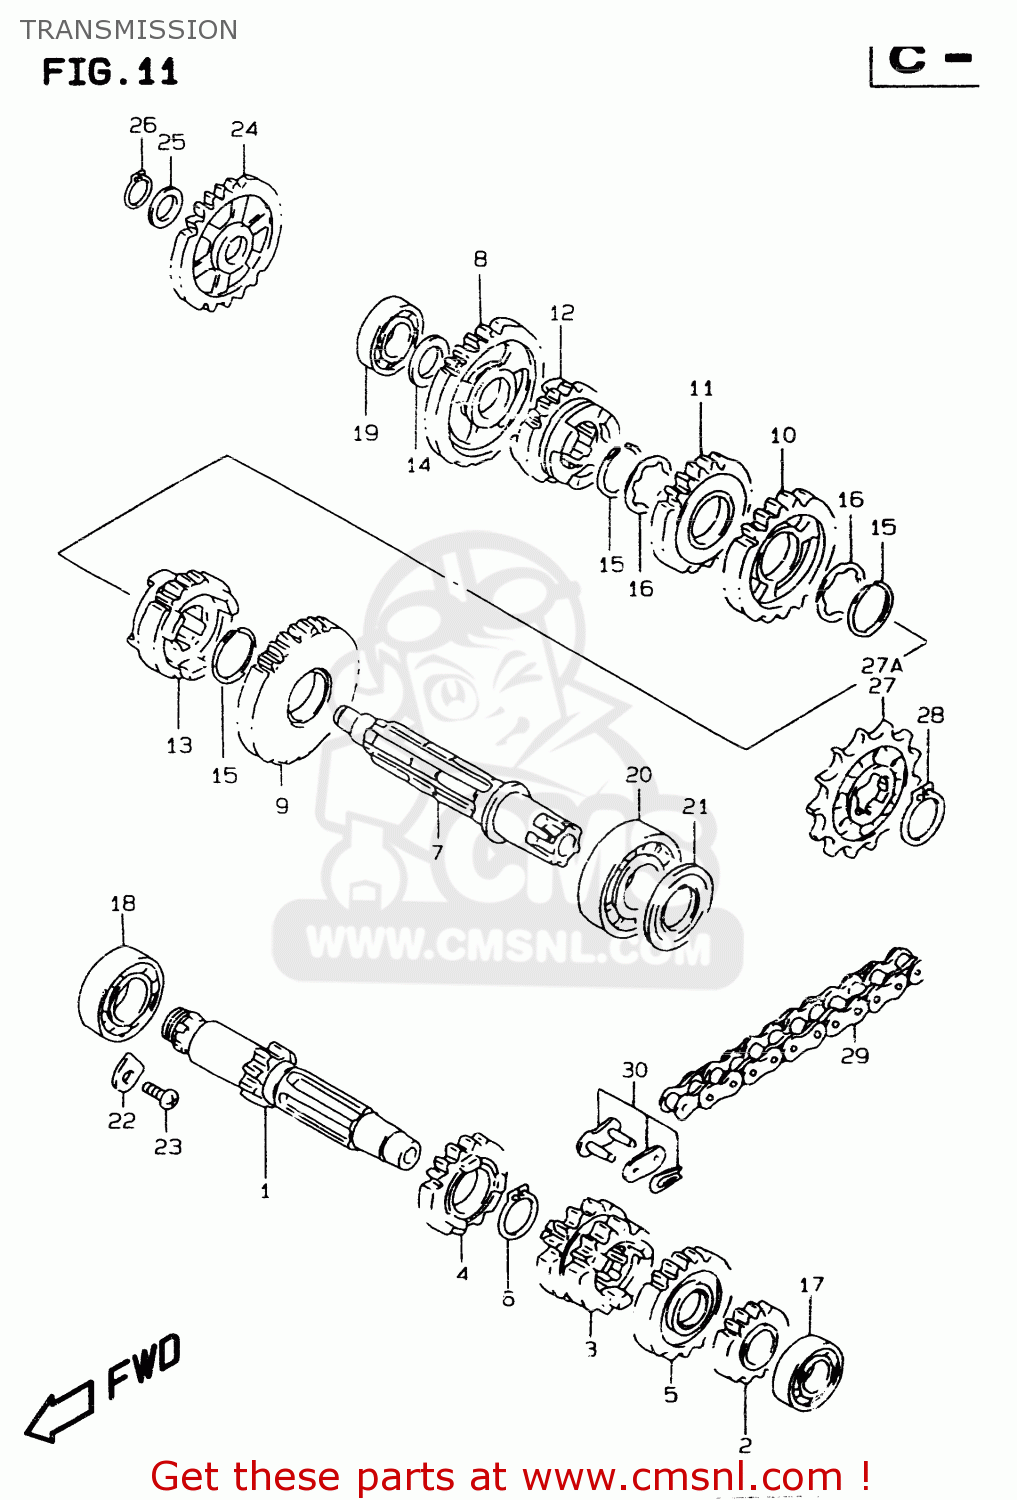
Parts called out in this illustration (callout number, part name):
1	SHAFT,COUNTER (NT:11)
2	GEAR,2ND DRIVE(NT:15)
3	GEAR,THIRD/FOURTH DRIVE
4	GEAR,FIFTH DRIVE
5	GEAR,6TH DRIVE
6	CIRCLIP
7	SHAFT,DRIVE
8	GEAR,FIRST DRIVEN
9	GEAR,SECOND DRIVEN
10	GEAR,THIRD DRIVEN (NT:22)
11	GEAR,FOURTH DRIVEN (NT:20)
12	GEAR,FIFTH DRIVEN
13	GEAR,6TH DRIVEN(NT:23)
14	WASHER,THRUST
15	CIRCLIP
16	WASHER,LOCK
17	BEARING
18	BEARING(20X42X12)
19	BEARING
20	BEARING(20X47X14)
21	OIL SEAL (20X35X5)
22	RETAINER
23	SCREW
24	GEAR,KICK STARTER IDLE(NT:24)
25	SHIM
26	CIRCLIP,12 MM
27	SPROCKET,ENGINE(NT:14)
27A	SPROCKET,ENGINE(NT:13)
28	CIRCLIP
29	CHAIN,DRIVE(428G2X118L)
30	JOINT SET,CHAIN
